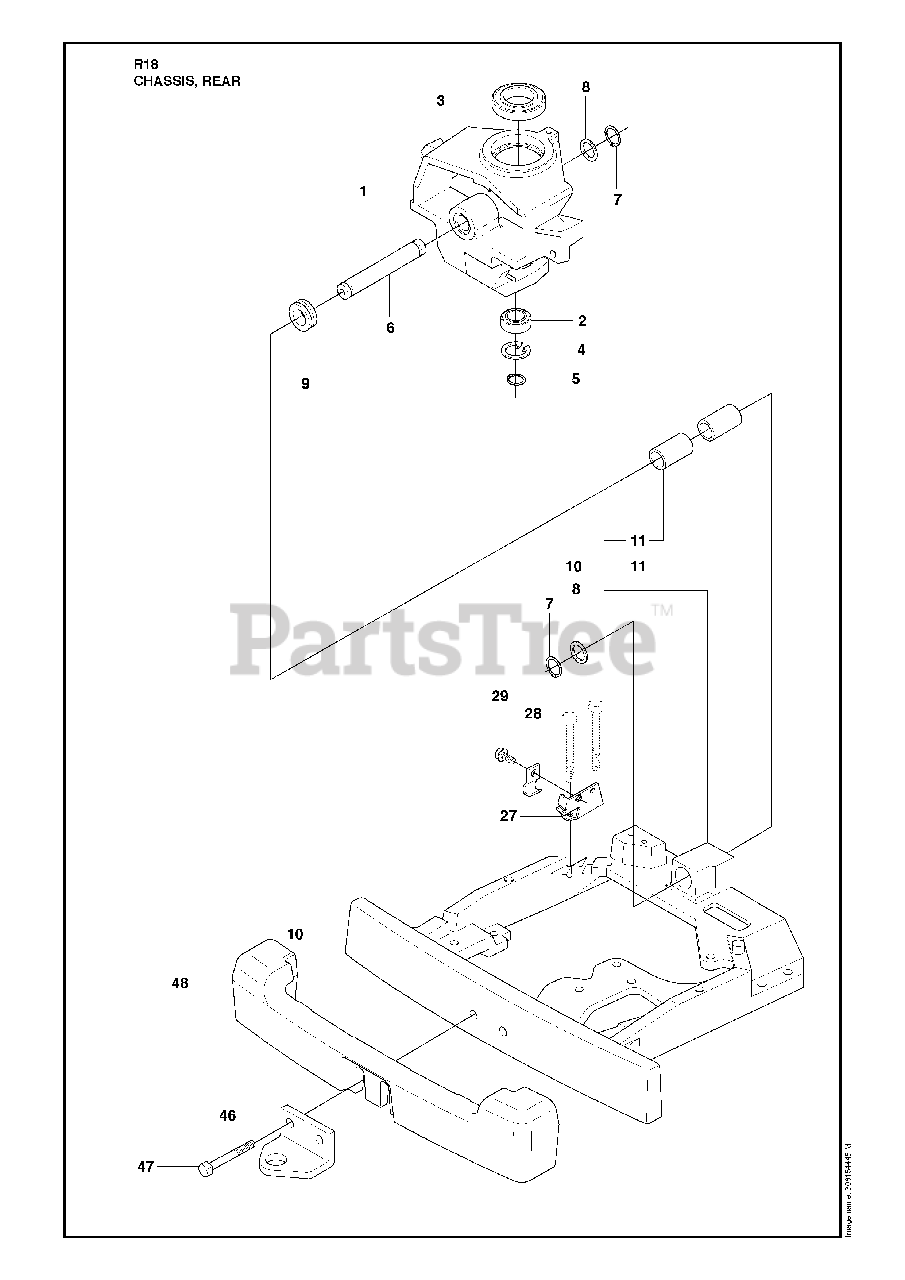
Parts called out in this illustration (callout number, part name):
2	Ball Bearing
3	BALL BEARING 6010 2RS1
4	CIRCLIP SGH 47
5	RETAINING RING SGA 25
7	RETAINING RING SGA 25
12	HYDROSTAT 7A646024070
15	WASHER BRB 8.4X17
16	NUT
21	NUT
23	WASHER
24	SCREW 8X20
26	LOCKNUT M5
33	TENSIONER
35	SCREW
37	LOCKNUT M8
38	WASHER
39	SCREW 8X20
43	NUT
45	TANK CAP
47	REPL BY 725 25 00-71
48	COUNTERWEIGHT
